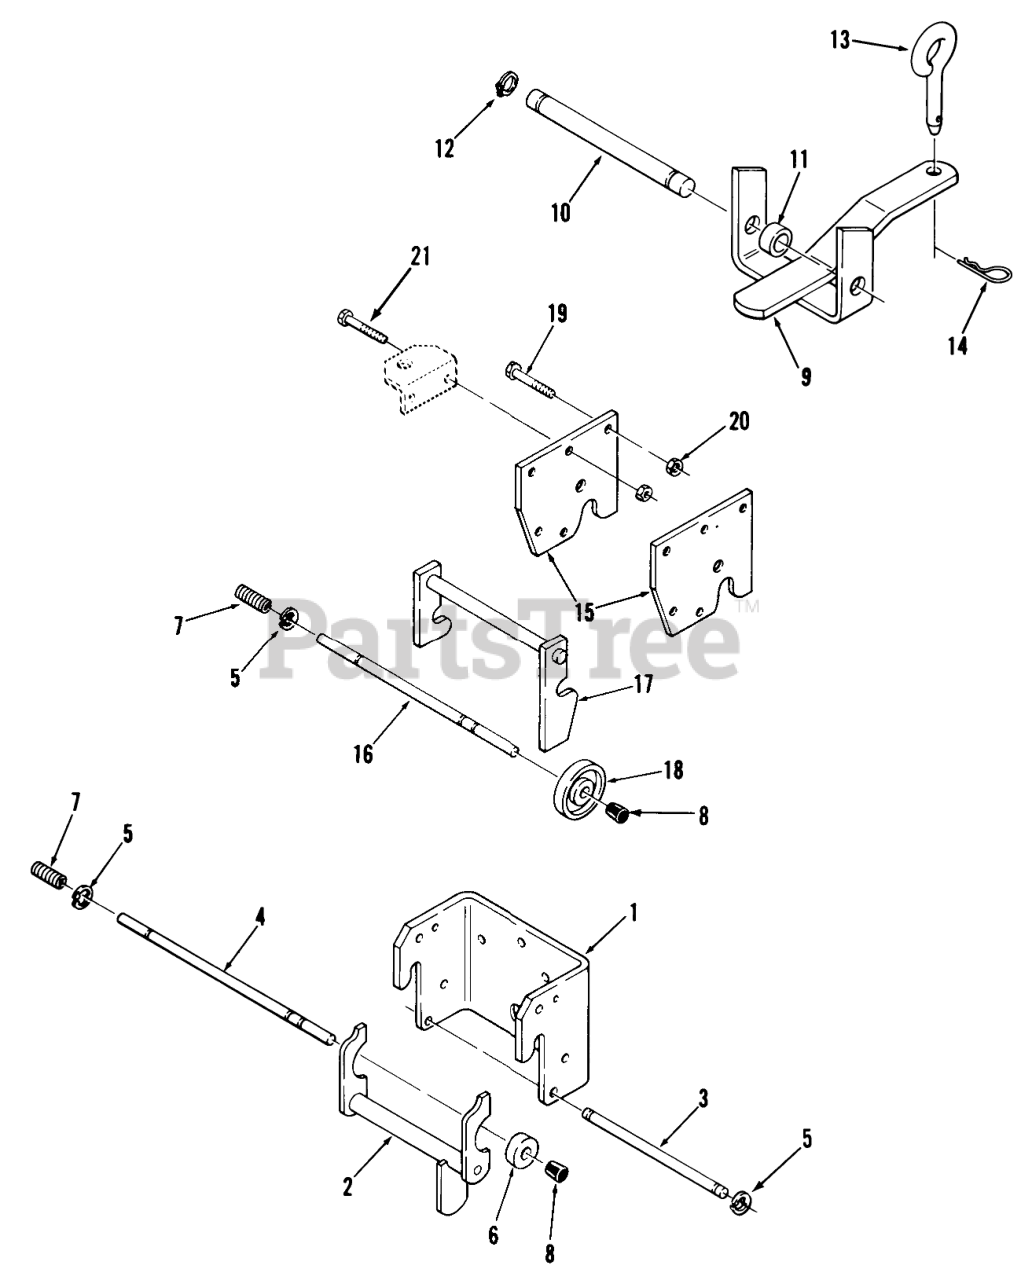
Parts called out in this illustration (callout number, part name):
1	Front Hitch
2	Assy-Latch
3	ROD-LATCH PIVOT
4	ROD-LOCK
5	RING-RETAINING
7	SPRING
8	CAP-ROD, PLUNGER
9	Hitch
10	PIN-STATIONARY HITCH
11	Spacer
12	E-RING
13	PIN-TOOL
14	Hairpin Cotter
15	Hitch Plate
17	ASSY MID HITCH LA R
19	BOLT
20	Nut
21	Bolt
